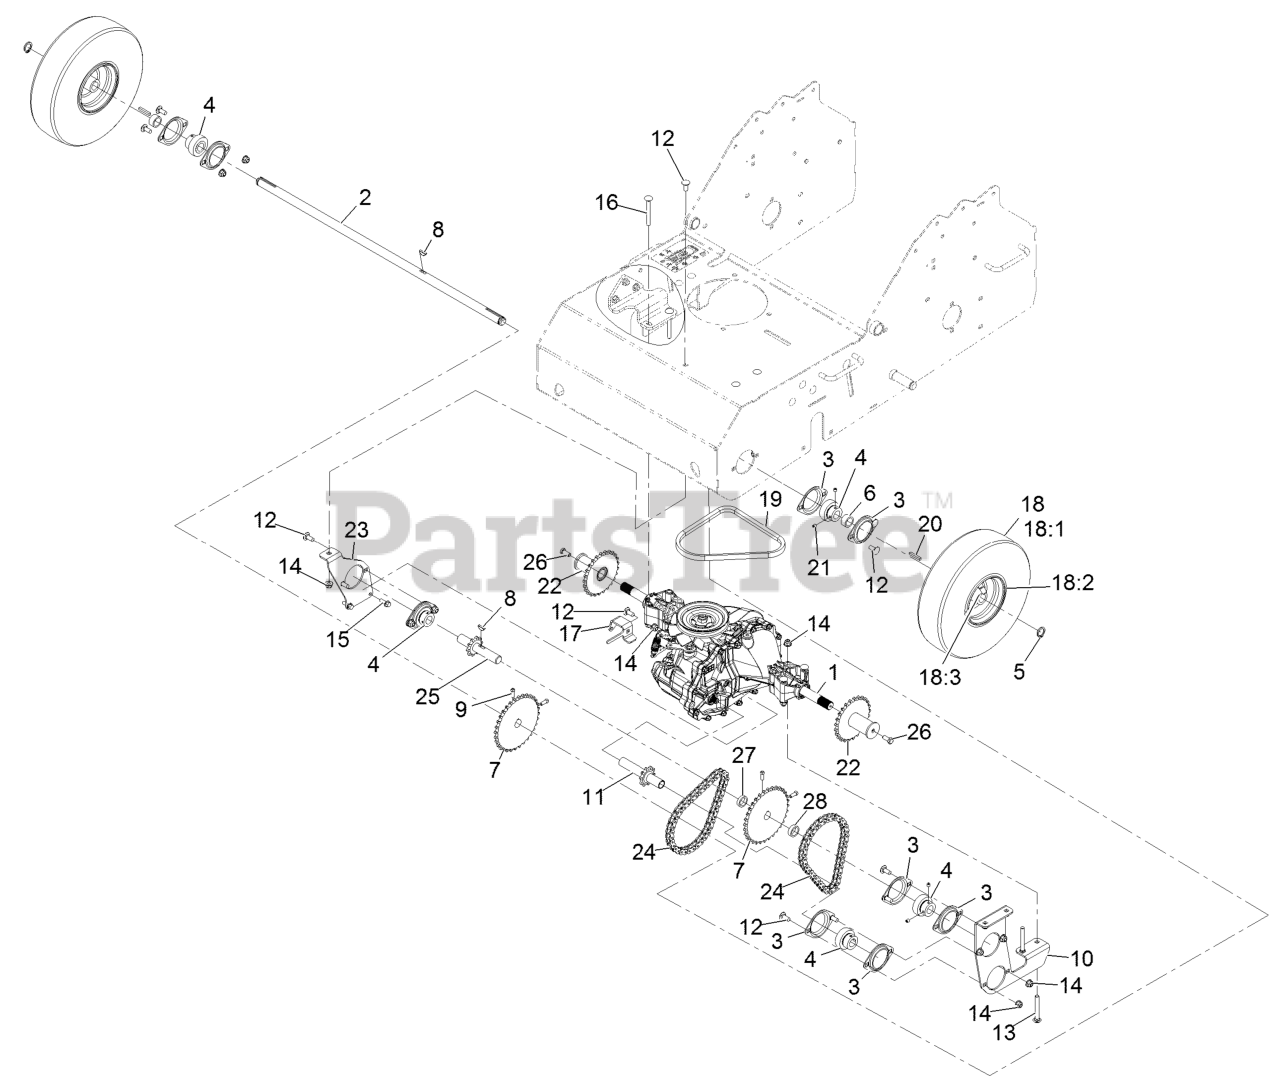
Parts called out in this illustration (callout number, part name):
1	TRANSAXLE ASM
2	SHAFT-WHEEL
3	FLANGE-BEARING
4	BEARING-LOCK, COLLAR
5	RING-RETAINING
6	SPACER-WHEEL
7	SPROCKET
8	KEY-WOODRUFF
9	SCREW-SET
10	PLATE-BEARING
11	SHAFT-OUTPUT
12	SCREW-CARR
13	SCREW-CARR
14	NUT-HF, NI
15	SCREW-HHF
16	SCREW-CARR
17	ANGLE-CONTROL
18	WHEEL ASM
18:2	WHEEL-RIM
18:3	VALVE
19	BELT-DRIVE
20	KEY-SQUARE
21	SCREW-SET, HSH
22	SPROCKET
23	BRACKET-SUPPORT, SHAFT
24	CHAIN-DRIVE WHEEL
25	SHAFT-JACK
26	SCREW-HH
28	SPACER-CONTROL
